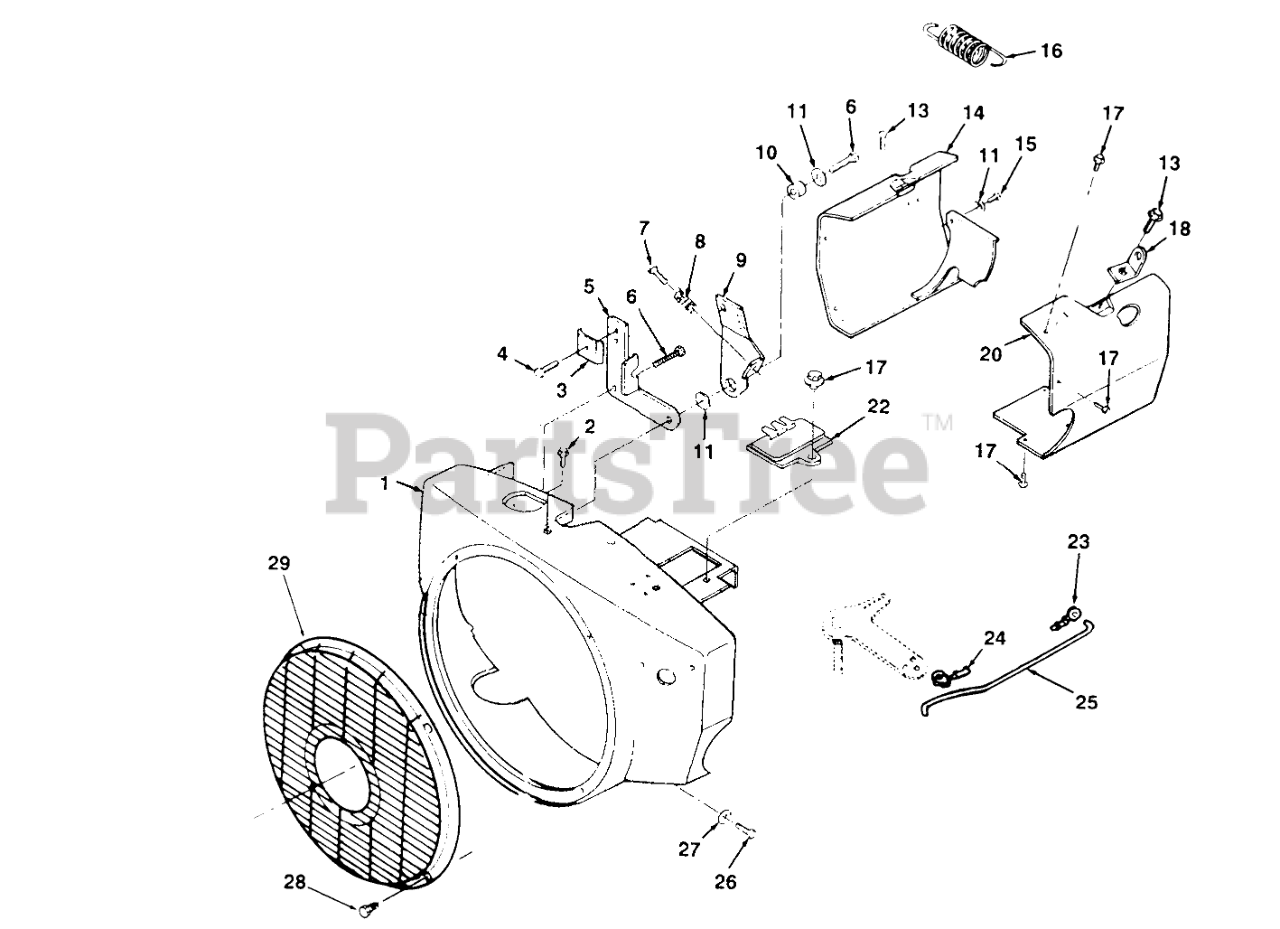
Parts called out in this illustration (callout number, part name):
1	HOUSING-BLOWER
2	SCREW-HWH
4	SCREW-TAPPING
5	BRACKET-GOVERNOR
6	SCREW-HWH
7	SCREW-TAP
8	SPRING
10	BUSHING
11	WASHER-FLAT
13	SCREW-HWH
14	HOUSING-AIR CYLINDER, LH
15	SCREW-HH
16	SPRING
17	SCREW-HWH
18	BRACKET-LIFTING
20	HOUSING-AIR CYLINDER, RH
22	REGULATOR
25	ROD-GOV CONTROL
26	Screw-Tapping
27	WASHER-FLAT
28	SCREW-PAN HEAD
29	GUARD-STATIONARY
